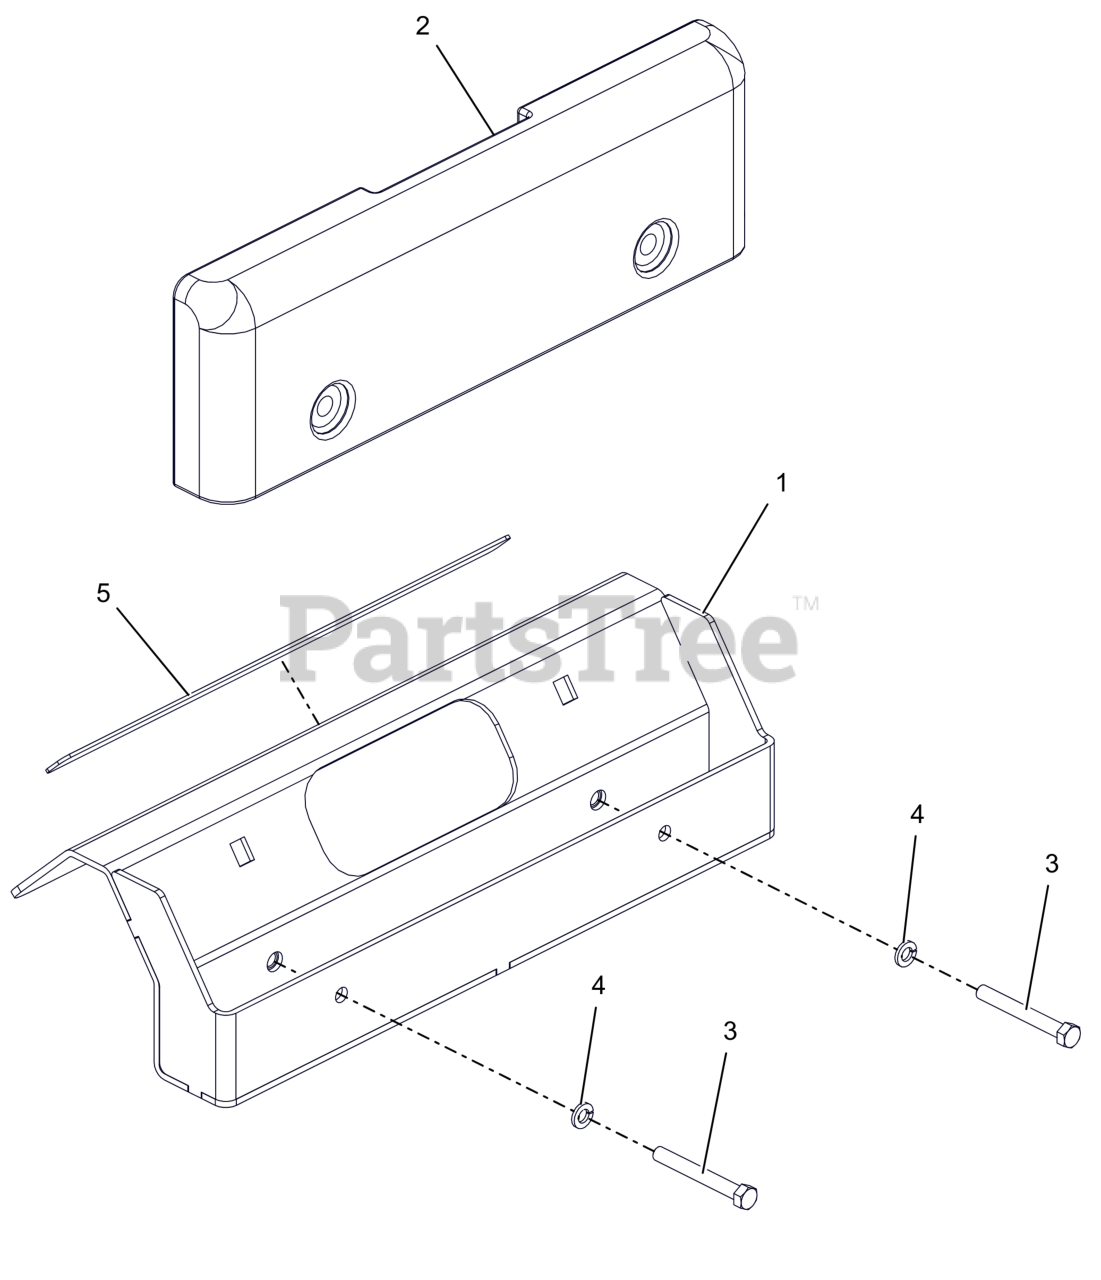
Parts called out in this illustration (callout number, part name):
1	WMT, BAGGER WEIGHT
2	WEIGHT, CAST IRON
3	BLT, HEX .38-16X3.00 G5 ZCC
4	WSHR,LK-REG .375X.094 ZCC
5	GRIP, ADHESIVE (1" X 16" BLK)
